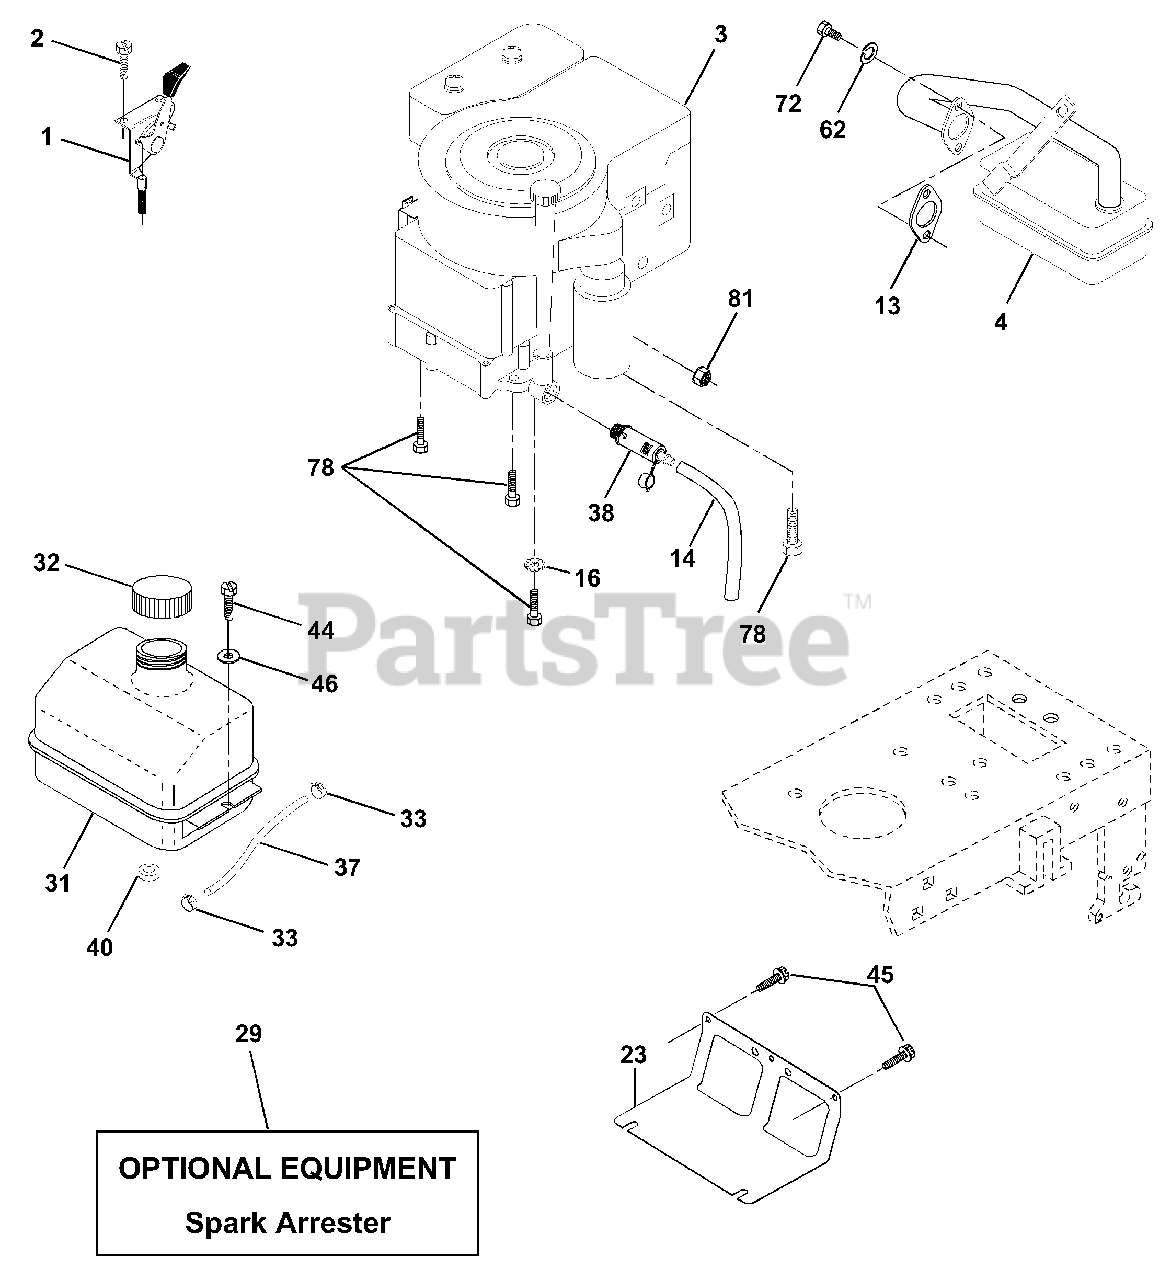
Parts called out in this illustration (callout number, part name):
1	Control Throt /Ch Flag
2	Screw Hex Thd Cut 1/4-20x5/8 T
4	Muffler Exhaust B&S Lt
13	Gasket 1 313 Id Tin Plated
14	Tube Drain Oil Easy
16	Washer Lock Ext Tooth 3/8
23	Shield Browning/Debris Guard
29	Arrestor Spark
31	Tank Fuel 1 25 Fr
32	Cap Asm Fuel W/sym Vented
33	Clamp Hose Blk
37	Line Fuel 20"
38	Plug Drain Oil Easy
40	Bushing Snap Nyl Blk Fuel Line
44	Screw Hexwsh Thdrol 1/4-20x3/4
45	Screw Hex Wsh Thdrol 3/8-16
46	Washer 9/32 X 7/8 X 16ga
62	Washer Lock Hvy Hlcl Spr 5/16
72	Screw Hexhd Cap 5/16-18 x 3/4
78	Screw Thdrol 3/8-16 x 1-1/4
81	Nut Keps Hex 1/4-20 Unc
